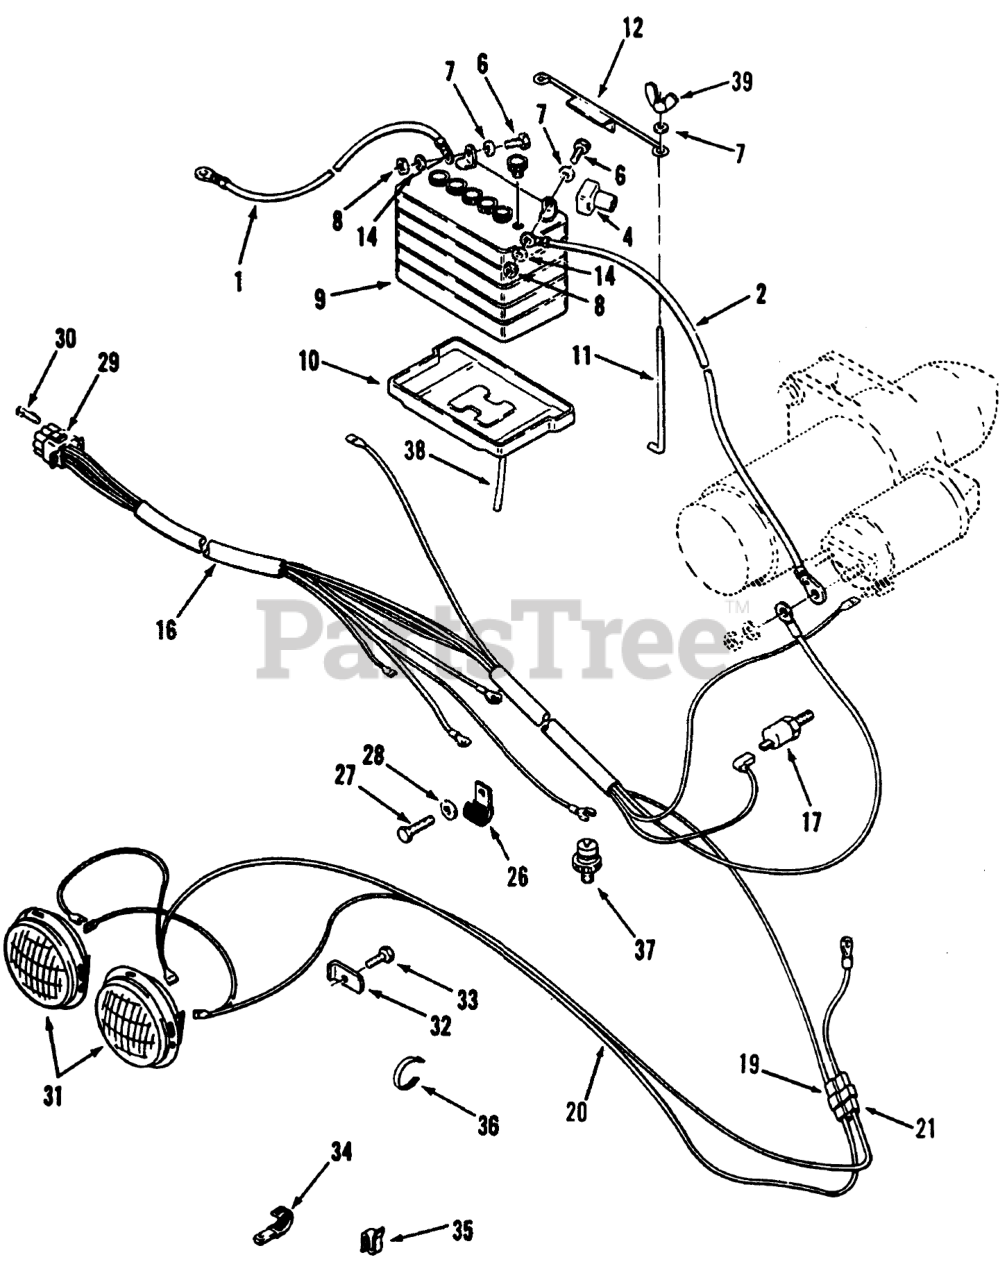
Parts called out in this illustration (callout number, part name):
1	ASS'Y-WIRE
2	ASS'Y-WIRE
4	Boot
6	SCREW-HH
7	WASHER-FLAT
8	NUT-LOCK, NI
9	Battery
10	THRUST WASHER
11	HOOK-BATTERY RETAIN
12	HOLDDOWN-BATTERY
14	WASHER-LOCK
16	WIRING HARNESS
17	HIGH TEMPERATURE
19	MALE CONNECTOR
20	HARNESS-HEADLIGHT
21	CONNECTOR BODY
26	CLIP-WIRE
27	SCREW-HWH
28	LOCKWASHER 1/4 IT
29	CONNECTOR CAP
30	CONTACT SOCKET
31	HEADLAMP
32	LOCK-HEADLIGHT
33	Bolt
34	CLIP
35	SPEED CLIP
36	PLASTIC TIE
37	SWITCH
38	TUBE-21" BATTERY DRAIN
39	NUT-WING
40	ELBOW-45 DEG
